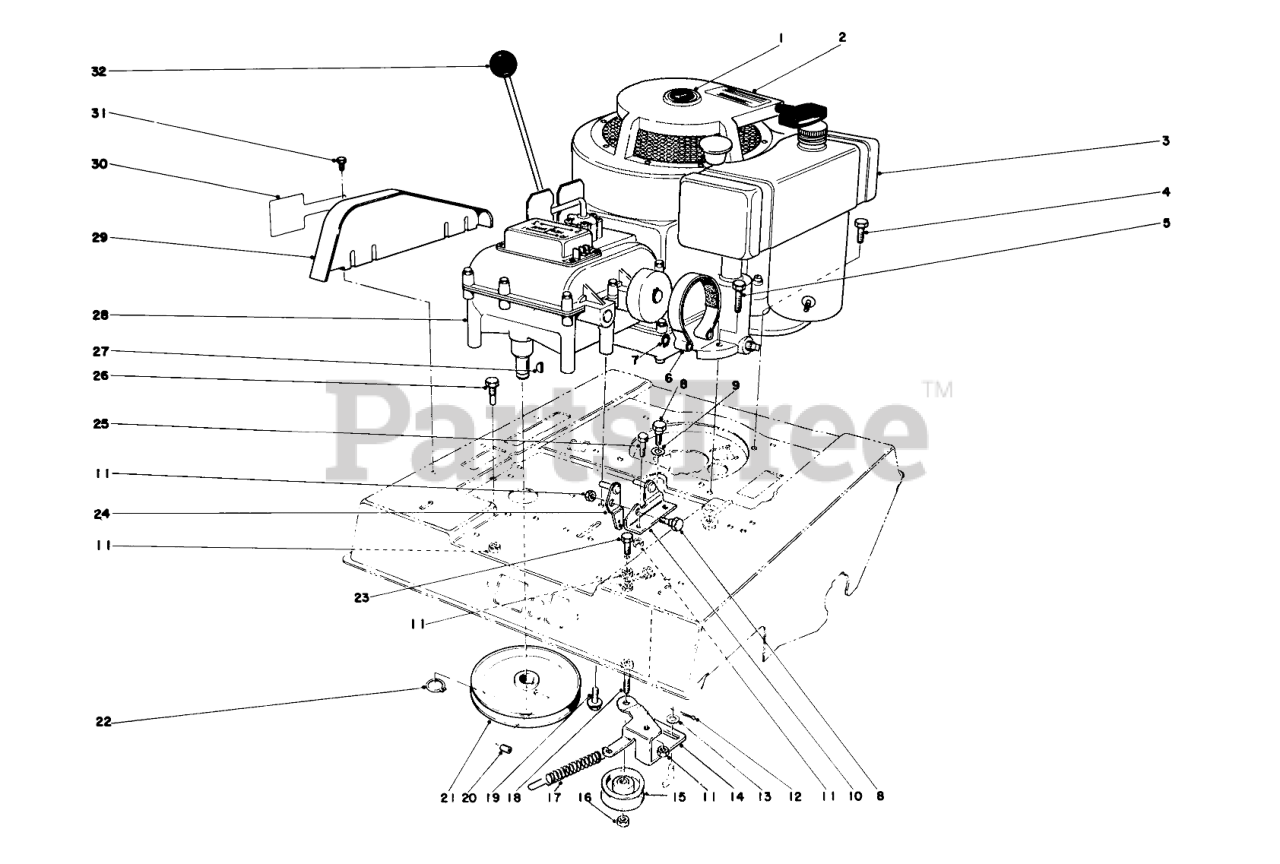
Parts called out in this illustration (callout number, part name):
1	Decal
2	Caution Decal
3	Engine
4	SCREW-HH
5	SCREW-HH
6	Brake Band
7	RING-GRIP
8	Screw
9	Washer
10	Bracket
11	NUT-LOCK, CONE
12	PIN-COTTER
13	WASHER-PLAIN
14	Idler Lever
15	PULLEY IDLER
16	NUT-LOCK, CONE
17	Clutch Spring
18	Capscrew
19	SCREW-HHF
20	SCREW-SET
21	Pulley
22	RING-SNAP, EXTERNAL
23	SCREW-HH
24	Pivot
25	SCREW-HH
26	Screw
27	KEY-WOODRUFF
28	Transmission
29	Chain Guard
30	Decal Shift Pattern
31	SCREW-HWH
